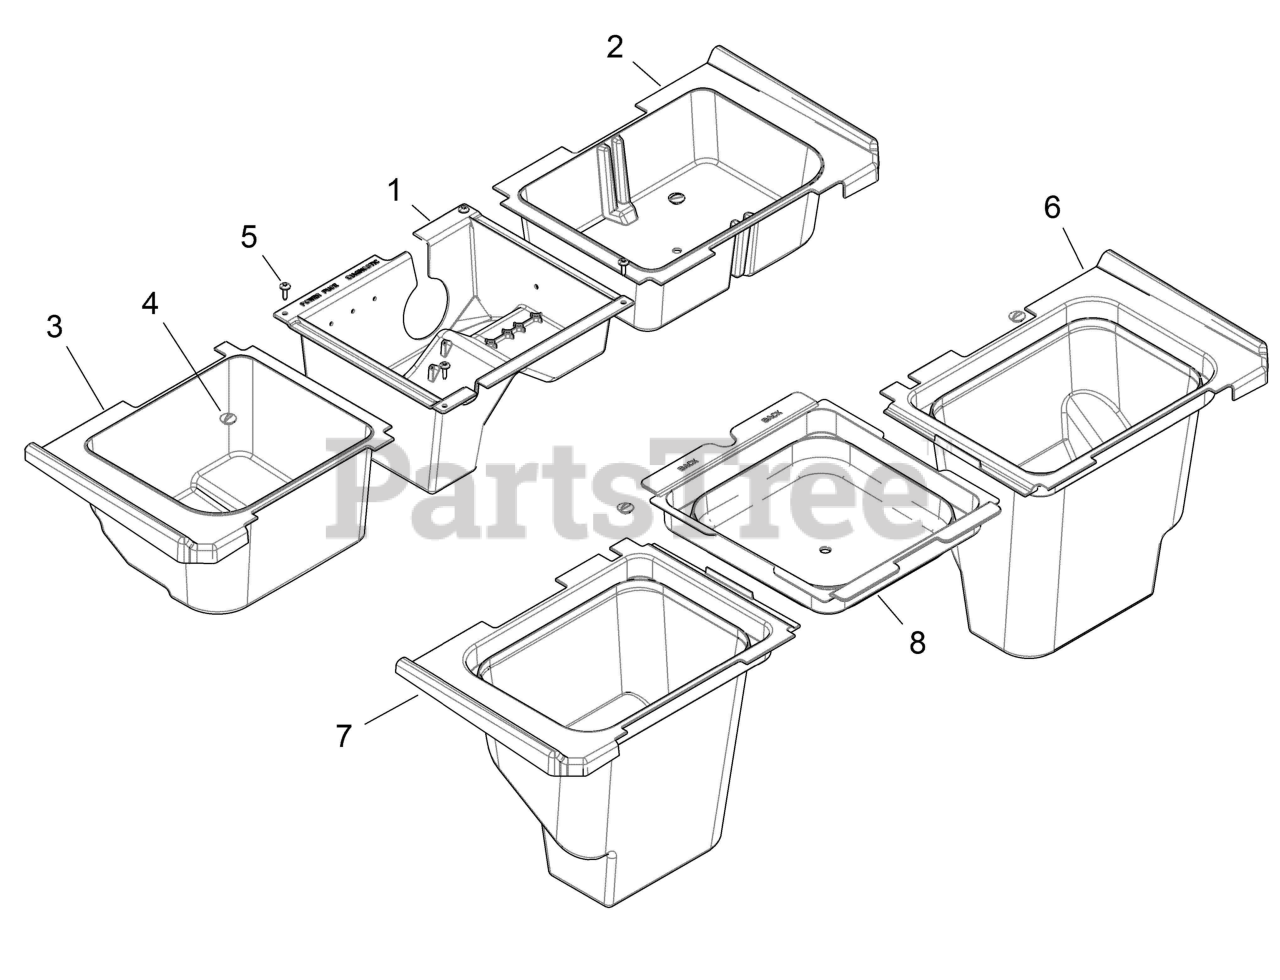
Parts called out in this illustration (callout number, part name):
1	STORAGE BOX,CENTER,BLK
2	STORAGE BOX,LH,BLK
3	STORAGE BOX,RH,BLK
4	PLUG-COMPARTMENT
5	SCR-TXTH-M6X1.0X25 RIE
6	STORAGE BOX,LH,BLK
7	STORAGE BOX,RH,BLK
8	BOX, STORAGE, CENTER, BLACK
